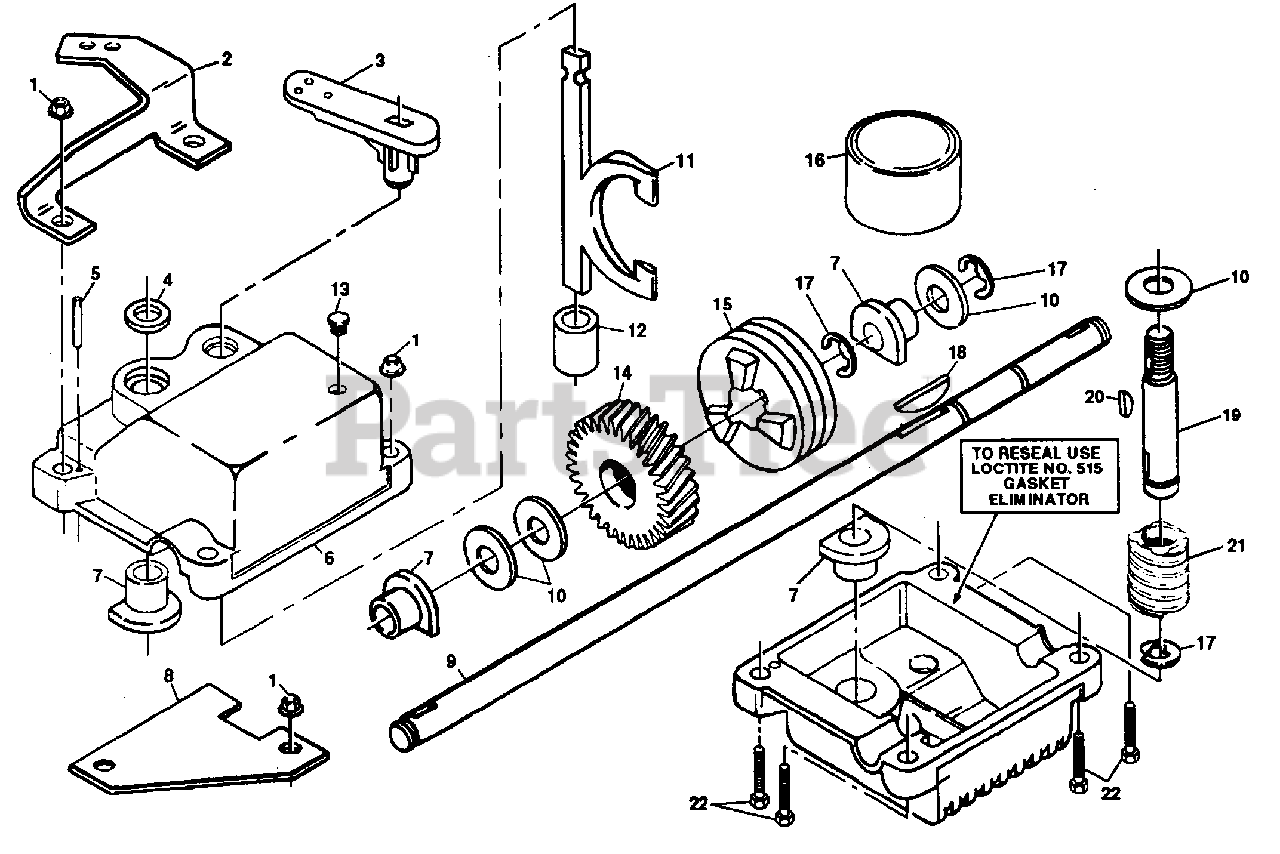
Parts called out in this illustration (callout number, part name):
1	Locknut, Keps 1/4-20
2	Bracket, Adjusting
3	Shifter
4	Seal
5	Pin, Grooved 1/8 x 1/2
6	Gear Case Halves, Upper and Lower
7	Bearing
8	Bracket, Spring
9	Drive Shaft
10	Washer, Hardened
11	Yoke, Clutch
12	Bushing
13	Plug
14	Gear, Helical
15	Jaw, Clutch
16	Grease
17	E-Ring
18	Key, Hi-Pro
19	Shaft, Worm
20	Key, Woodruff, #3
22	Screw, Hex Head 1/4-20 x 1-1/4
